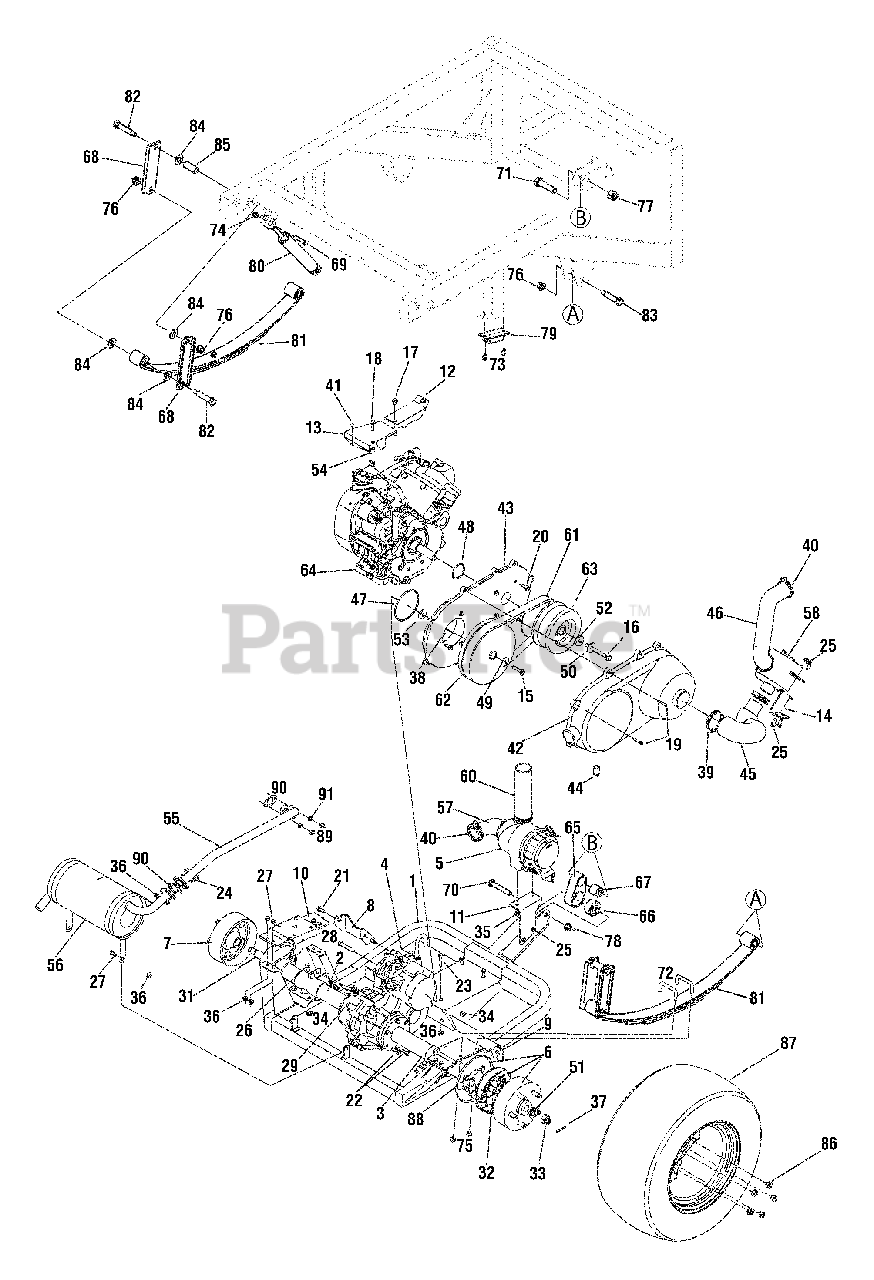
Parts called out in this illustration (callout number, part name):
3	Pipe Assembly - RH
4	Kawasaki Gear Assembly
5	Kawasaki Filter Housing Assembly
6	Brake Assembly w/Drum - RH
6	Brake Assembly w/Out Drum - RH
7	Brake Assembly w/Drum - LH
7	Brake Assembly w/Out Drum - LH
8	Transmission Bracket
13	Cont: Cvr
14	Kawasaki Filter Bracket
15	Hex Screw, M8-1.25
16	Hex Flange Screw, M10 x 102MM
17	Hex Flange Screw, M8-1.25
18	Hex Flange Screw, 8MM x 1.125
19	Hex Flange Screw, M6 x 1.00
20	Flange Screw, M8 x 1.125
21	Flange Screw, M8 x 1.125
22	Flange Screw, M8 x 1.125
23	Hex Screw, 5/16-18 x 1.50
24	Hex Screw, 5/16-18 x.875
25	Screw, 5/16-18 x.750
26	Hex Screw, 3/8-16 x.750
27	Hex Screw, 5/16-18 x.75
28	Hex Screw, 3/8-16 x 2.25
29	Hex Screw, M8-1.25
30	OPP 4X2 Shaft
31	OPP Transmission Axle - LH
32	OPP Transmission Axle - RH
33	Nut, M18-1.5
34	Flange Lock Nut, 3/8-16
35	Hex Nut, M8-1.25
36	Flange Lock Nut, 5/16-18
37	Cotter Pin, 5/32 x 1.25
38	Kawasaki Key
39	Adj. Hose Clamp
40	Hose Clamp
42	Case - RH
43	Case - LH
44	Boot
45	Duct
46	Duct
47	Kawasaki O-Ring
48	Kawasaki O-Ring, 50 x 4
49	Kawasaki Washer, 8.5 x 38 x 4
50	Kawasaki Washer, 10 x 32 x 4.5
51	Washer, 34MM x 18MM x 4MM
52	Kawasaki Spacer w/ Key
53	Kawasaki Spacer
54	Spacer, 9 x 13 x 17.2
55	Kawasaki Exhaust Pipe
56	Kawasaki Exhaust Muffler
57	Kawasaki Air Filter Hose
58	Kawasaki Air Filter Assembly 11010-1735
60	Kawasaki Airbox Hose
61	Kawasaki Belt
62	Kawasaki Driven Pulley
63	Kawasaki Drive Pulley
64	Engine
65	Bushing Plate w/bushing & bearing
66	Bushing
67	Bearing, 63ID x 1.19OD x 1.25
68	Shackle Plate
69	Hex Screw, 3/8-16 x 1.75
70	Hex Screw, M12-1.75 x 75MM
71	Hex Screw, 5/8-11 2.5 Lg.
72	OPP Transaxle U Bolt
73	Self Tap Screw, 1/4-20 x.500
74	Hex Lock Nut, 3/8-16
75	Hex Lock Nut, 3/8-24
76	Flange Lock Nut, 7/16-20
77	Hex Lock Nut, 5/8-11
78	Flange Lock Nut, M12-1.75
79	Extension Suspension Bumper
80	Shock Absorber, 2.50 Stroke
81	Leaf Spring
82	Shoulder Screw,.550 x 2.290
83	Shoulder Screw,.550 x 2.13
84	Thrust Bearing,.56 ID x 1.25OD x.06
85	Bushing,.75OD x.562ID x 1.75
86	Lug Nut, 7/16-20
87	Rim, Rear Wheel
88	Hex Screw, 10-1.25 x 16MM
89	Hex Nut, M8-1.25
90	Kawasaki Exhaust Pipe Gasket
91	Lock Washer, 8MM
